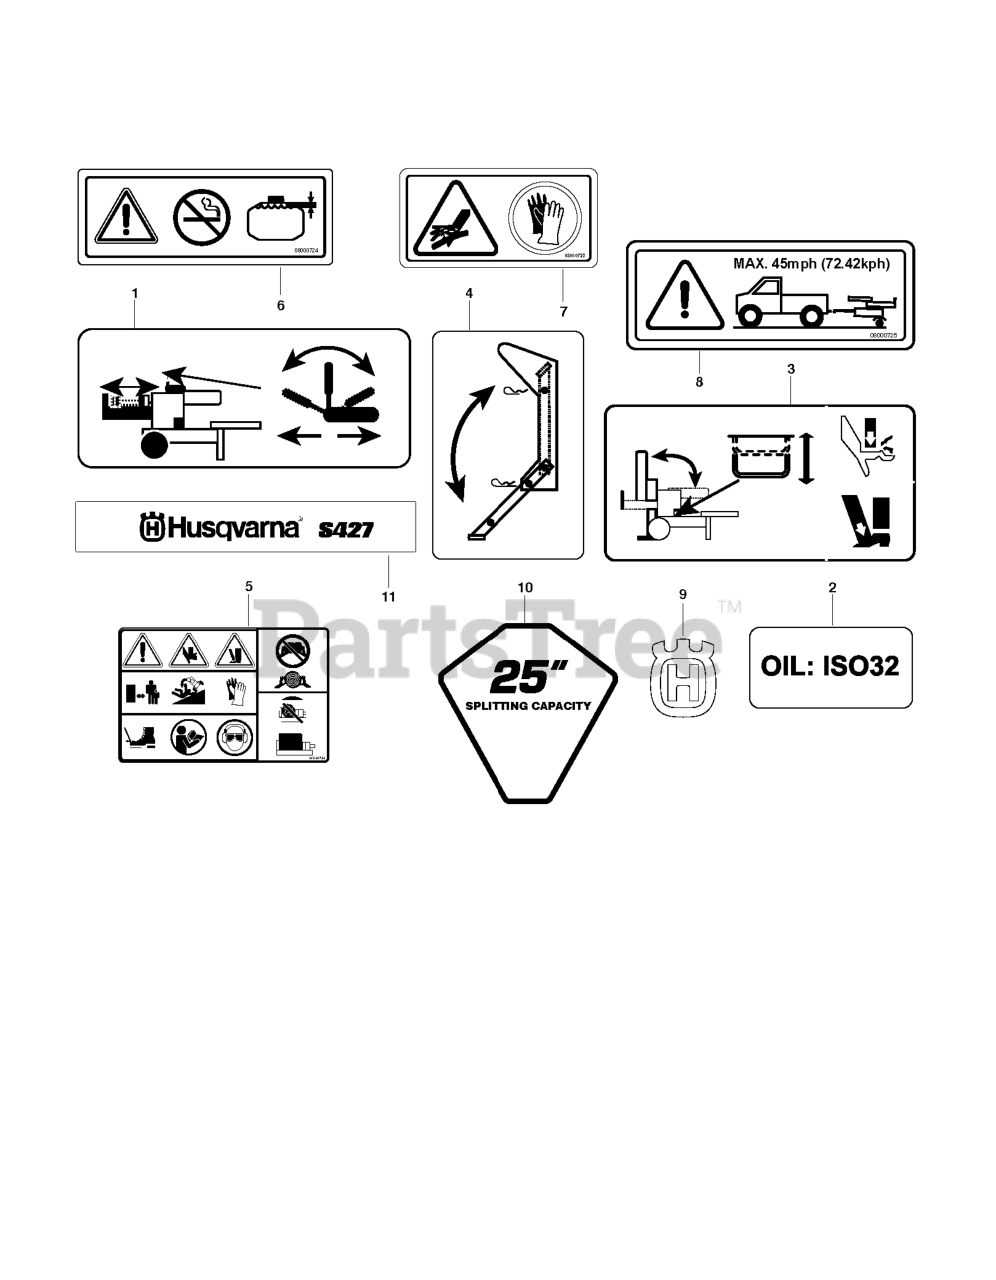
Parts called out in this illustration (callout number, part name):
1	DECAL DECAL, LOG SPLITTER-HYD
2	DECAL DECAL, LOG SPLITTER-RAM
3	DECAL DECAL, LOG SPLITTER-REAR
4	DECAL DECAL, LOG SPLITTER-TILT
5	DECAL DECAL,DANGER LOG SPLITTE
6	DECAL DECAL,FUEL WARNING
7	DECAL DECAL,HYD WARNING
8	DECAL DECAL,TOWING
9	DECAL.AUGER.HUSQ.CROWN.SNOW
11	DECAL, HUSQVARNA BRAND &
